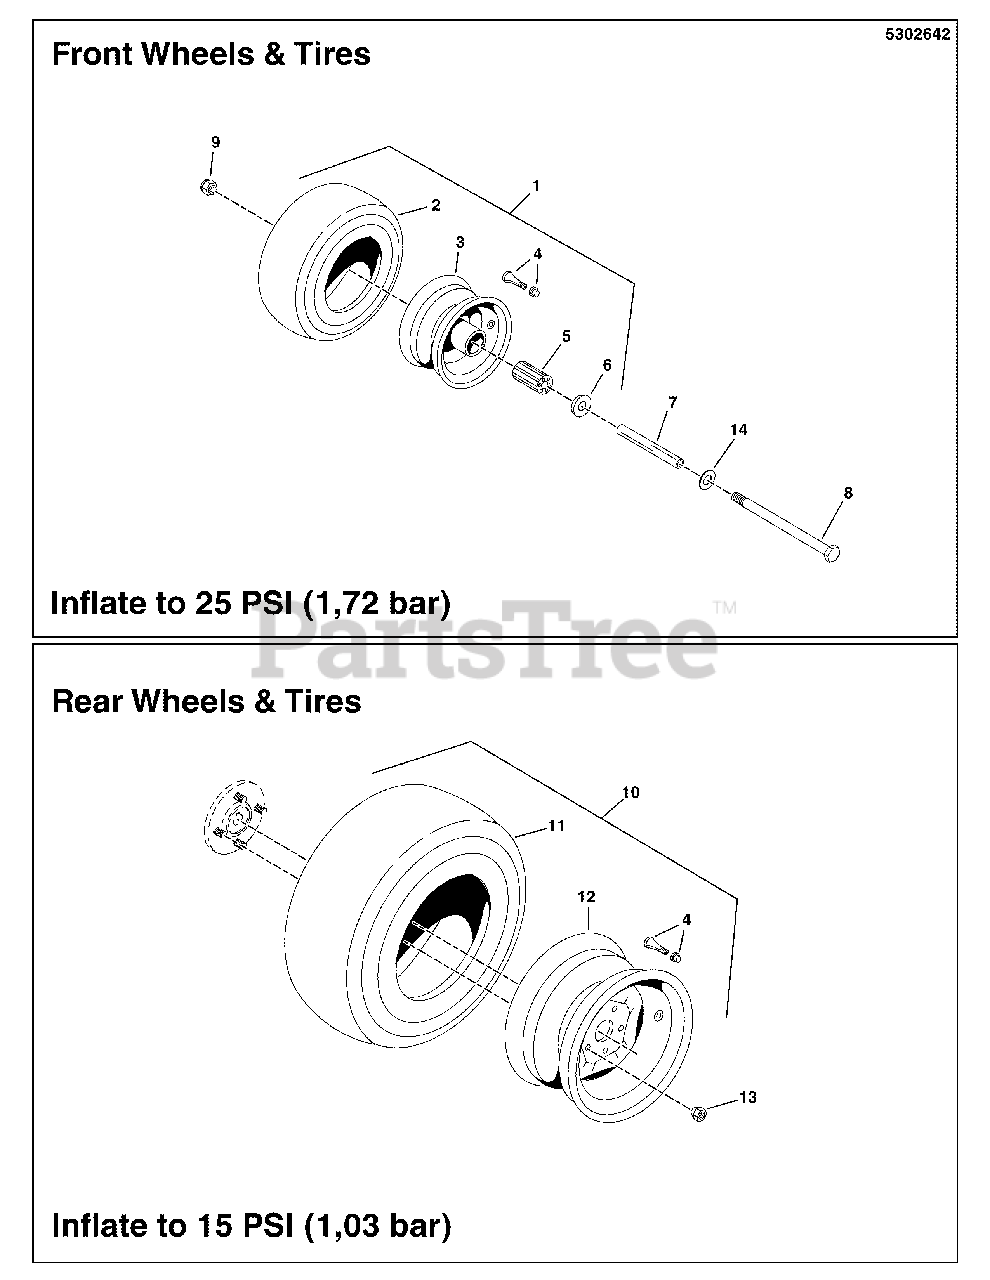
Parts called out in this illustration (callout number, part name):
1	WHEEL, CASTER, 11 X 4.0-5 SILVER BEAD LO
2	TIRE, 11 X 4.0-5
3	WHEEL ASSEMBLY, 11 X 4.0 - 5 TIRE CMP (SV)
4	VALVE STEM & CAP ASSEMBLY (SV)
5	BEARING, ROLLER (SV)
6	BEARING, CASTER WHEEL, 11 X 4.0 - 5 BEAD LOCK (SV)
7	CASTER AXLE DDSH
8	BOLT, 1/2-13 X 7 GD8 YZ
9	NUT, 1/2-13 HEX NYLOCK FLANGE
10	TIRE ASM, REAR, 20 X 10.0 X 10
11	TIRE, REAR, 20 X 10.0 X 10
12	WHEEL, 10X7.00 4/4 SOLID F237 2.625 OS (SV)
13	NUT, 1/2-20, FOR WHEEL BOLT SILVER
14	WASHER, 1/2 SAE
